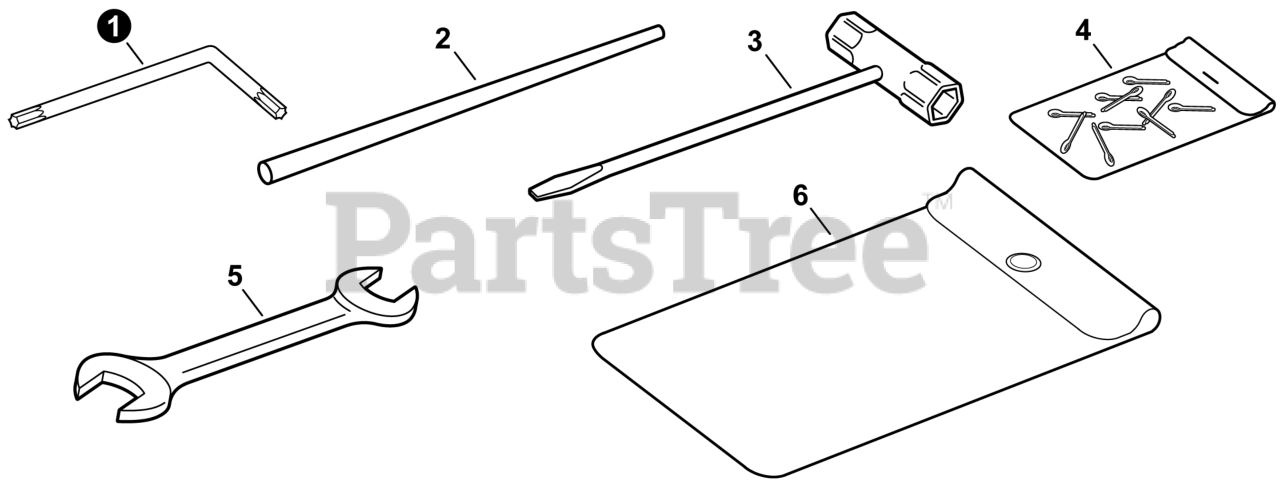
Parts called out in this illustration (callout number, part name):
1	WRENCH, T27 80x30
2	TOOL, LOCKING 5x120 MM
3	T-WRENCH 17x19 L200
4	PIN, COTTER 2x22 (PKG. OF 10)
5	SPANNER 8x10
6	BAG, TOOL
